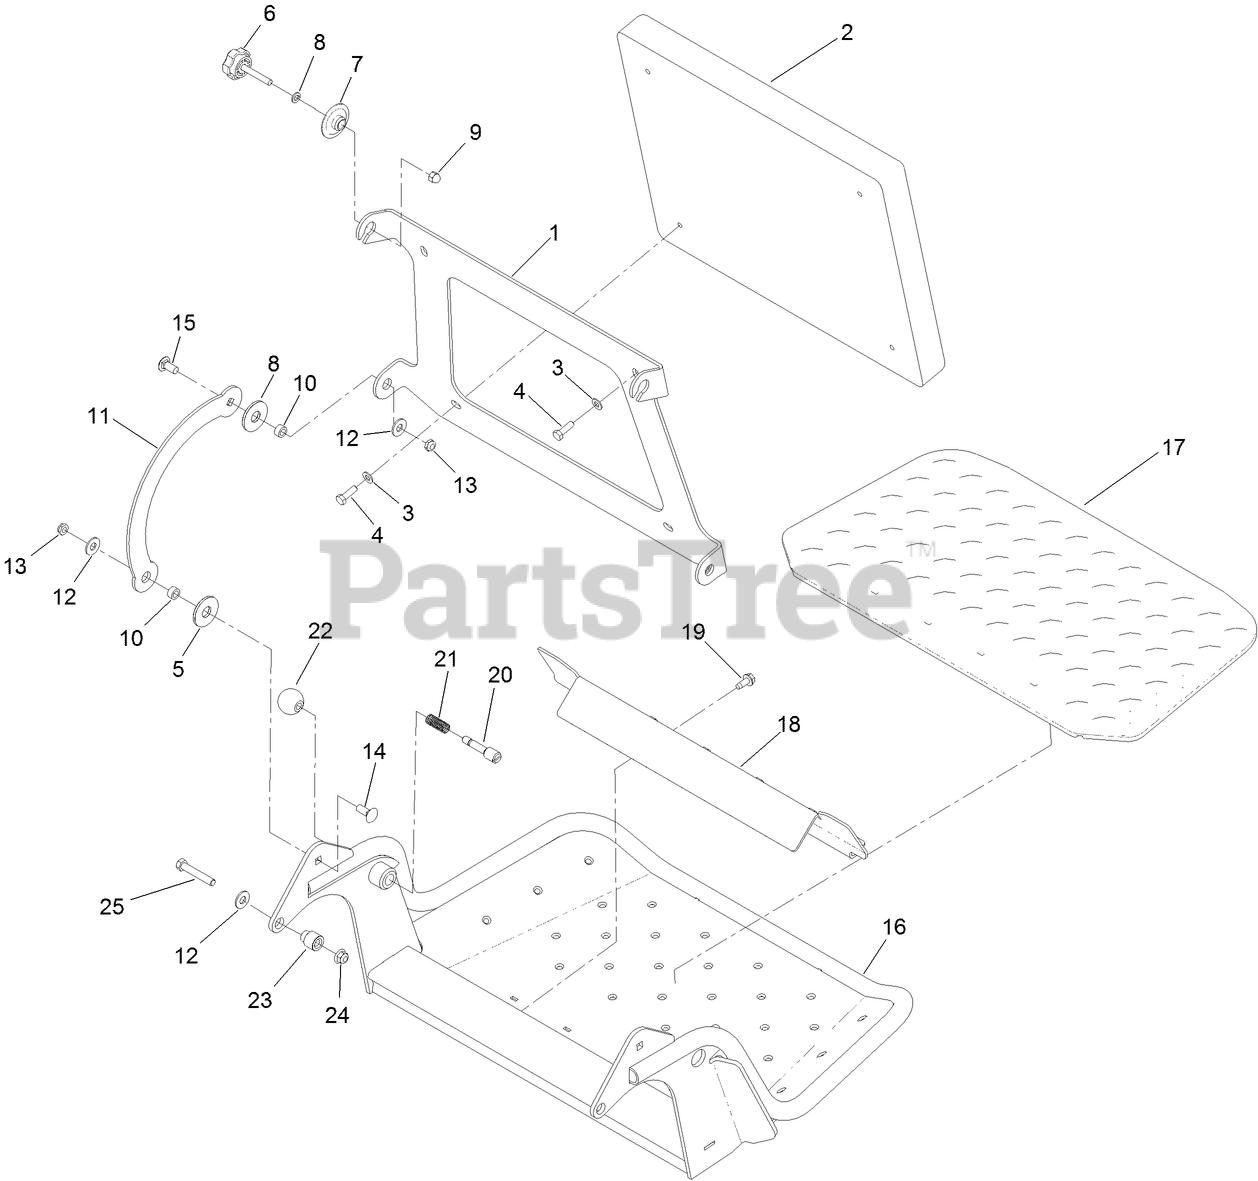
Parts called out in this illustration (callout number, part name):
1	HINGE-PAD
2	PAD-CUSHION
3	WASHER-PLAIN
4	SCREW-HH
5	WASHER-FRICTION, COMPOSITE
7	SLIDE-BUSHING
8	WASHER-LOCK
9	NUT-ACORN
10	SPACER
11	LINK-PAD
12	WASHER-FLAT
14	BOLT-CARR
15	SCREW-CARR
16	PLATFORM
17	MAT-PLATFORM
18	SHIELD CLAMP KIT
19	SCREW-HWHTF
20	PIN-LATCH
21	SPRING
22	KNOB-BALL
23	BUSHING-FLANGED
24	NUT-HF, NI
25	SCREW-HH
